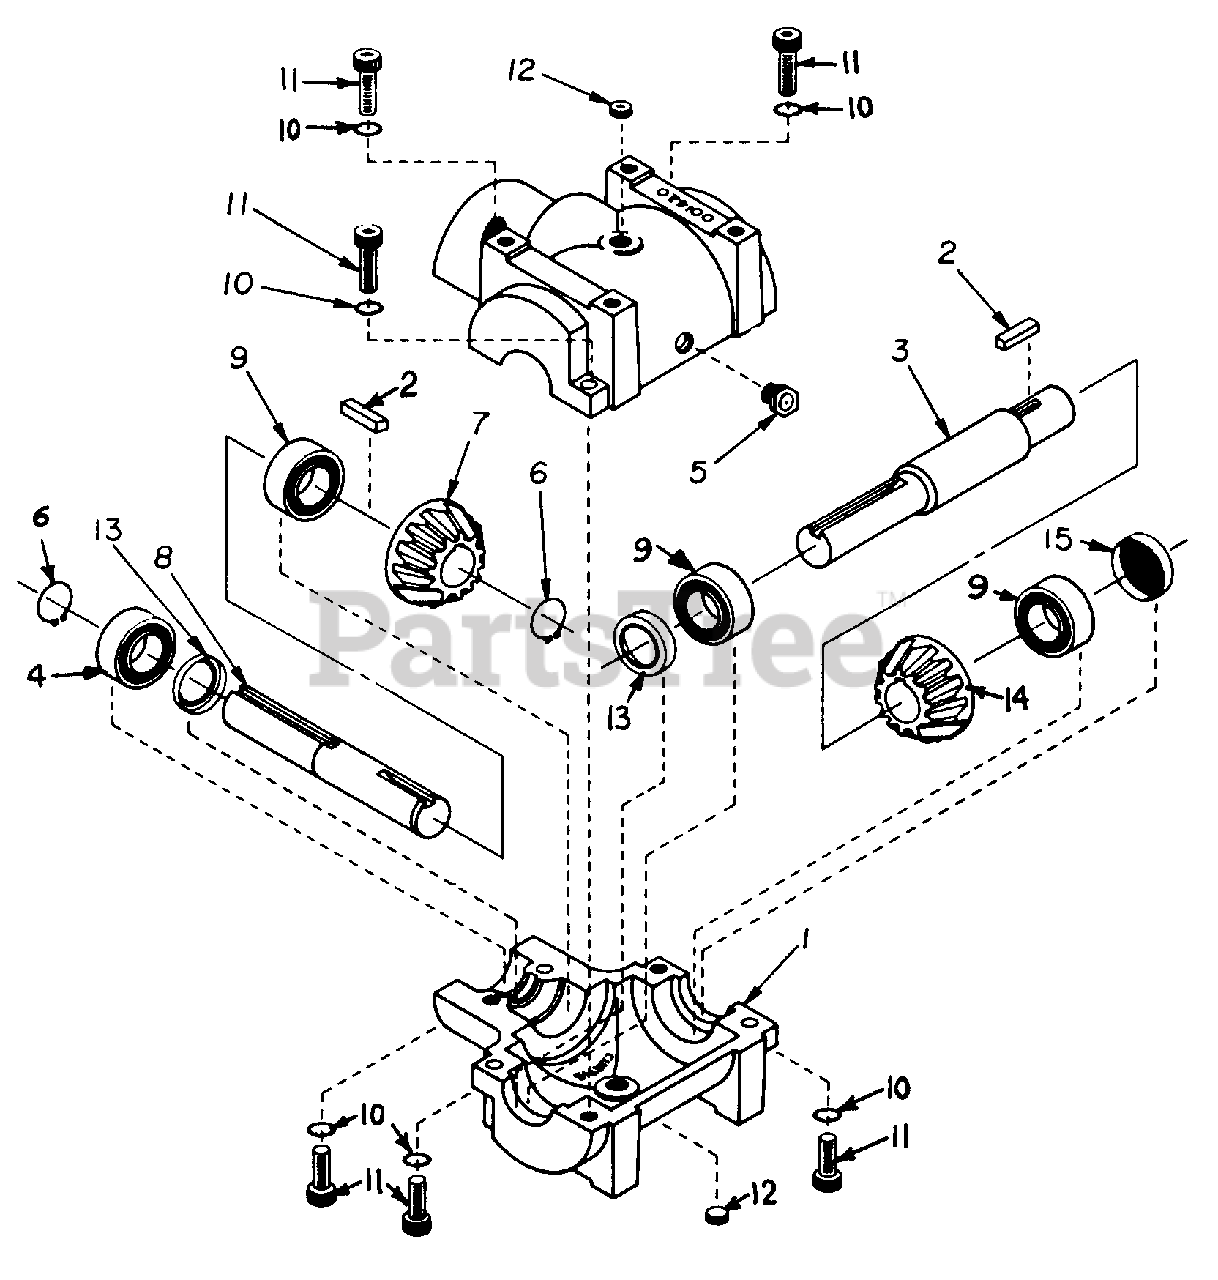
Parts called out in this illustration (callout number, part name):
2	Key, 3/16" x 3/16" x 1"
4	Ball Bearlng
5	Sockethead Plpe Plug, 1/4"
6	Retaining Rlng
7	Output Shaf t Gear
9	Ball Bearlng
10	Lockwasher
11	Allenhead Capscrew
12	Sockethead Plpe Plug, 1/4"
14	Input Shaft Gear
15	Expansion Plug
